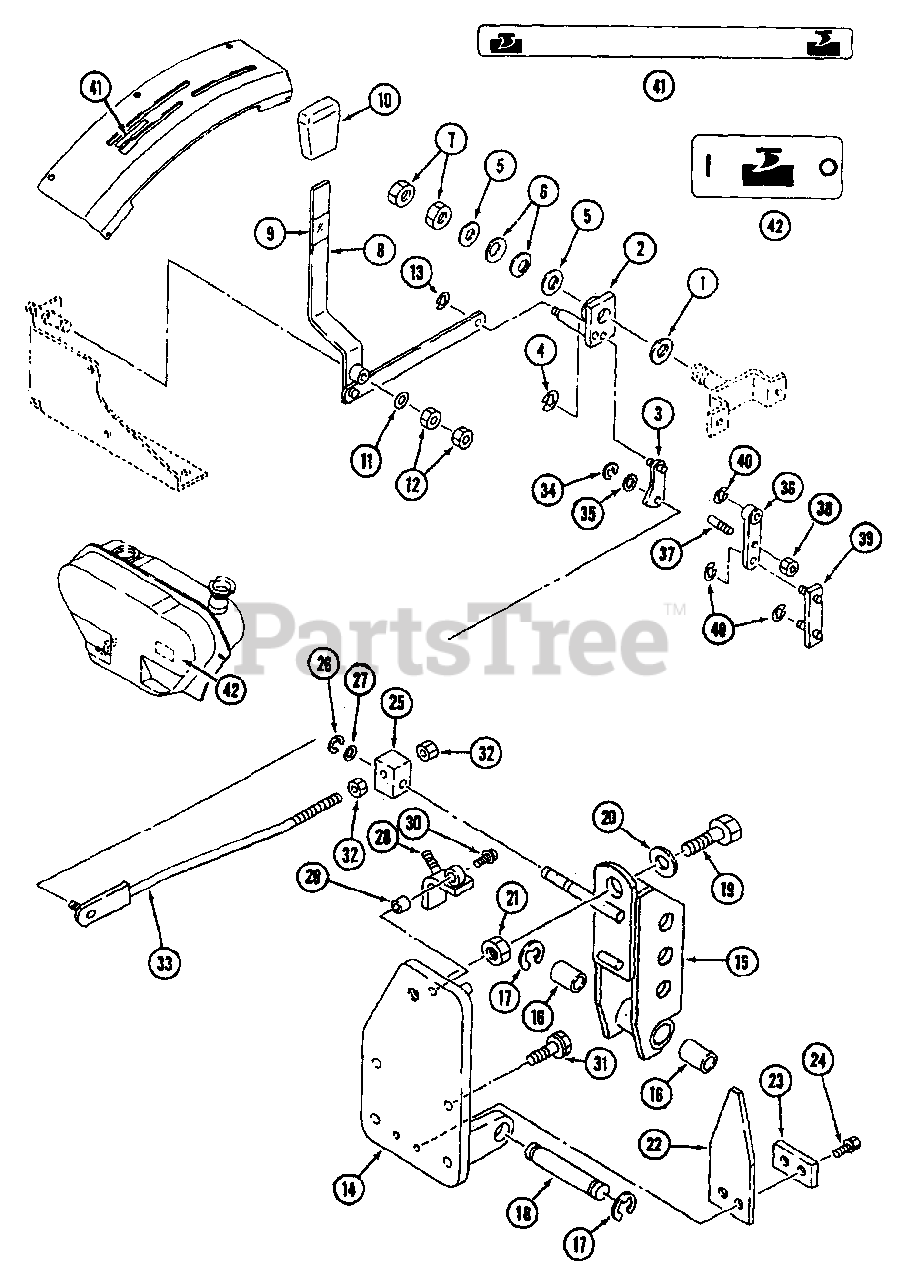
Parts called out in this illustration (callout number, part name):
8	Lever, D/C Ass'y.
15	Bracket, Toplink
42	Label, D.Lock
